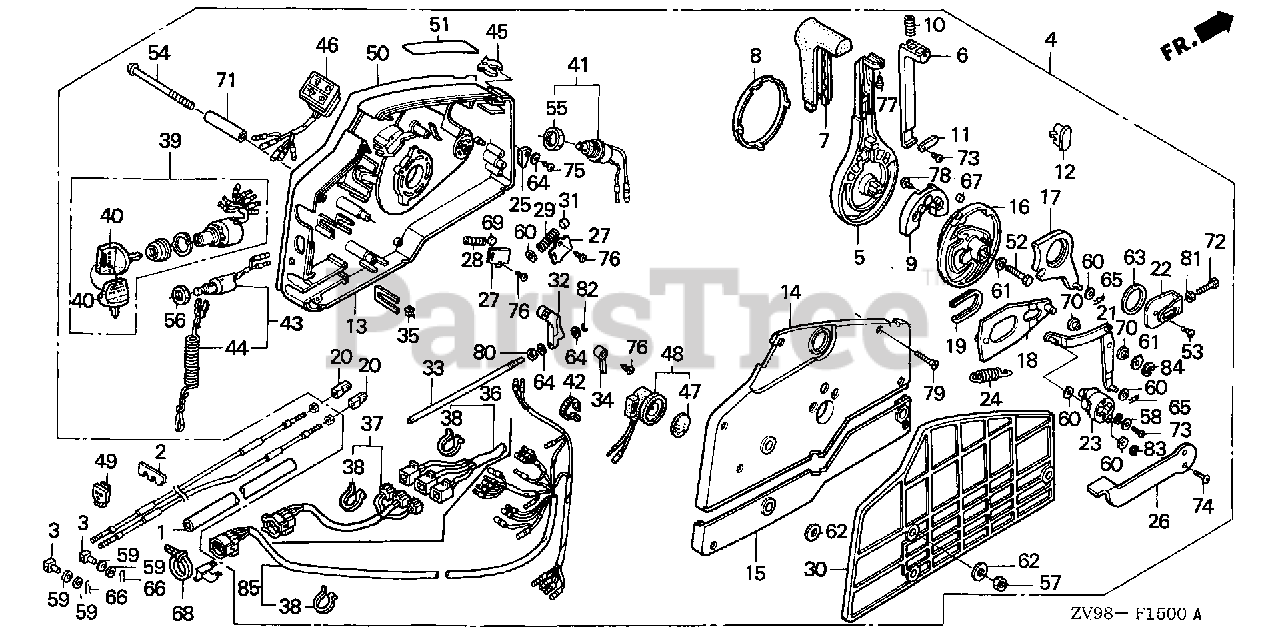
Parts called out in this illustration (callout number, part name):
1	TUBE, CORRUGATE (28MM)
2	PLATE, REMOTE CONTROL CABLE
3	PIVOT, SHIFT
4	BOX ASSY., REMOTE CONTROL
5	HANDLE, REMOTE CONTROL
6	LEVER, HANDLE LOCK
7	GRIP, REMOTE CONTROL HANDLE
8	CAP, HANDLE
9	BLOCK, NEUTRAL LOCK
10	SPRING, REMOTE CONTROL HANDLE
11	PLATE, LEVER SETTING
12	COVER, GRIP
13	HOUSING, REMOTE CONTROL BOX (A)
14	HOUSING, REMOTE CONTROL BOX (B)
15	HOUSING, REMOTE CONTROL BOX (C)
16	WHEEL, CONTROL
17	ARM, SHIFT LINK
18	PLATE, SLIDING
19	COLLAR, SLIDING PLATE
20	PIVOT, SHIFT
21	ARM, LINK JOINT
22	BRACKET, LINK JOINT
23	WHEEL, ACCELERATOR
24	SPRING, ACCELERATOR WHEEL
25	CAM, STARTER SWITCH
26	LEVER, IDLE
27	PLATE, SPRING SETTING
28	SPRING, SHIFT CLICK
29	SPRING, CHOKE RETURN
30	SPACER, REMOTE CONTROL BOX
31	SPACER, CLICK SPRING
32	BLOCK, THROTTLE FRICTION
33	BOLT, FRICTION
34	SPACER, NEUTRAL SWITCH
35	SPACER, CABLE CLAMP
36	CABLE ASSY., REMOTE CONTROL (B)
37	CABLE ASSY., SWITCH PANEL
38	TIE, CABLE (2.4X92) (NATURAL)
39	SWITCH ASSY., COMBINATION
40	KEY ASSY., COMBINATION SWITCH (35100-ZV5-003 ONLY)
41	SWITCH ASSY., SOLENOID
42	BAND (BLACK 3.5X140)
43	SWITCH ASSY., EMERGENCY STOP
44	WIRE, EMERGENCY
45	CLIP, EMERGENCY LOCK
46	LAMP ASSY., INDICATION (2-LED)
47	PLATE, TURN SIGNAL BUZZER
48	BUZZER, WARNING
49	GROMMET, CASE (LOWER) (A)
50	PLATE, REMOTE CONTROL (CAUTION PICT=SILVER)
51	MARK, FAST IDLE
52	BOLT, HEX. (8X35)
53	SCREW, PAN (6X10)
54	SCREW (6X95)
55	NUT, HEX. (20MM)
56	NUT, HEX. (16MM)
57	NUT, HEX. (6MM)
58	WASHER, PLAIN (5MM)
59	WASHER, PLAIN (6MM)
60	WASHER, PLAIN (6MM)
61	WASHER, PLAIN (8MM)
62	WASHER (6MM)
63	WASHER (28MM)
64	WASHER, PLAIN (4MM)
65	PIN, LOCK (6MM)
66	PIN, SPECIAL LOCK (6MM)
68	BAND, SELF-LOCK
69	ROLLER, CLICK
70	COLLAR, LINK JOINT
71	COLLAR, DISTANCE (6X10X43.5)
72	BOLT, HEX. (5X16)
73	SCREW, PAN (5X10)
74	SCREW, OVAL (5X12)
75	SCREW, TAPPING (4X10)
76	SCREW, TAPPING (5X10)
77	SCREW, TAPPING (5X12)
78	SCREW, TAPPING (6X16)
79	SCREW, TAPPING (5X25)
80	NUT, HEX. (6MM)
81	NUT, HEX. (5MM)
82	E-RING (3MM)
83	E-RING (4MM)
84	E-RING (7MM)
85	CABLE ASSY., REMOTE CONTROL (B)
